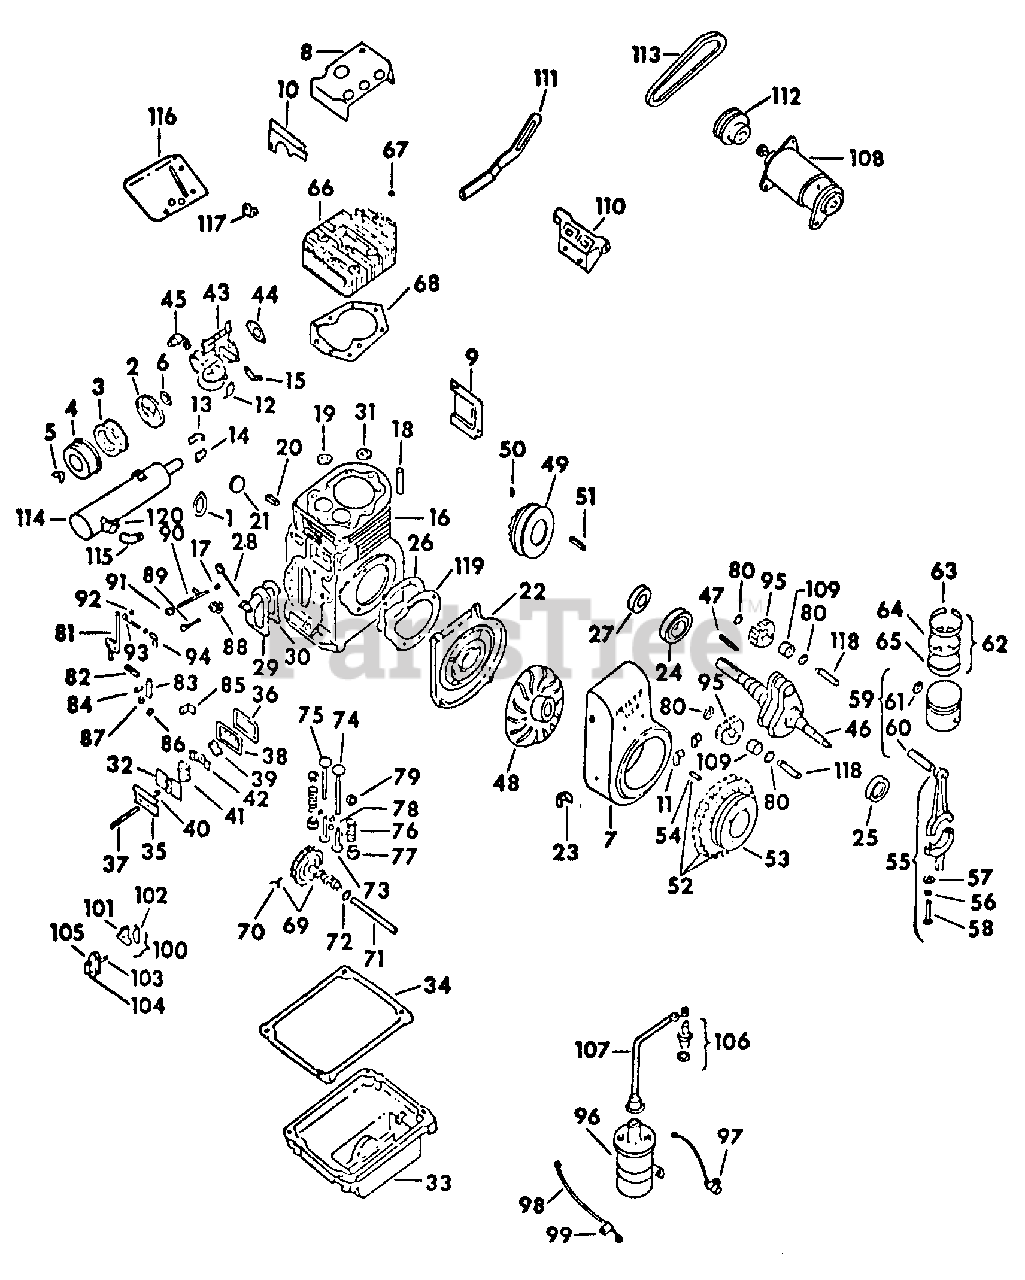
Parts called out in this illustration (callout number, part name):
1	Nut, Exhaust Muffler Elbow Lock
2	Base, Air Cleaner
3	Element, Air Cleaner Filter
4	Cover, Air Cleaner
5	Nut, Air Cleaner Wing
6	Gasket, Air Cleaner
7	Housing Assy, Blower
8	Baffle, Cylinder Head Air
9	Baffle, Cylinder Air
10	Baffle, Housing Side Air
11	Clip, Throttle Cable
12	Clip, Choke Cable
13	Bracket, Throttle Cable
14	Clip, Throttle Cable
15	Bracket, Choke
16	Block, Cylinder
17	Bearing, Needle
18	Guide, Valve
19	Insert, Exhaust Valve
20	Shaft, Governor
21	Plug, 1-1/8 Expansion (Crankcase)
22	Plate, Crankcase Bearing
24	Bearing, Crankcase Ball
25	Seal, Front Plate Oil
26	Gasket, Bearing Plate, .010
27	Seal, Crankcase Rear Oil
29	Cover, Camshaft
30	Gasket, Camshaft Cover
31	Insert, Intake Valve
32	Gasket, Valve Cover
33	Base, Oil Pan
34	Gasket, Oil Pan Base
35	Cover, Breather
36	Gasket, Breather
37	Stud, Breather Cover
38	Plate Assy, Breather
39	Reed, Breather
40	Seal, Breather
41	Filter, Breather
42	Baffle, Breather
43	Carburetor Assy
44	Gasket, Carburetor
45	Elbow, Carburetor to Fuel Line
47	Key, 3/16 X 3/8 Sq Parallel
49	Pulley w/Clutch Drive Plate, Flywheel
50	Screw, Flywheel Pulley Set
51	Key, 1/4 X 7/8 Sq Parallel
52	Cup Assy, Flywheel Drive
53	Screen, Drive Cup Grass
54	Pin, Flywheel Drive Cup
55	Rod Assy, Connecting, Std
56	Washer, Connecting Rod Lock
57	Washer, Connecting Rod
58	Screw, Connecting Rod
59	Piston Assy, Std
60	Pin, Piston
61	Retainer, Piston Pin
62	Ring Set, Piston, Std
63	Ring, Top Compression
64	Ring, Center Compression
65	Ring, Oil Control
66	Head, Cylinder
67	Washer, Cylinder Head
68	Gasket, Cylinder Head
69	Camshaft Assy
70	Spring, Camshaft Actuating
71	Pin, Camshaft
72	Shim, Camshaft, .005
73	Tappet Assy, Valve
74	Valve, Intake
75	Valve, Exhaust
76	Spring, Valve
77	Rotator, Valve
78	Key, Valve Spring
79	Retainer, Valve Spring Upper
80	Kit, Spacer
81	Lever, Governor
82	Spring, Governor
83	Bracket, Speed Control
84	Clamp, Control Bracket
85	Bracket, Adjusting Screw
86	Spacer, Adjusting Screw
87	Washer, Adjusting Screw Spacer
88	Gear Assy, Governor
89	Pin, Governor Stop
90	Shaft Assy, Governor Cross
91	Bushing, Cross Shaft
92	Rod, Ball Joint Throttle
93	Retainer, Throttle Rod
94	Joint, 10-32 X 1/4 Ball
95	Gear Assy, Crankshaft Balance
96	Coil, Ignition
97	Condenser, Ignition Coil
98	Cable Assy, Condenser to Breaker
99	Clip, Condenser to Breaker Cable
100	Not used in this application
101	Breaker Contact Set
102	Bracket, Breaker Point
103	Rod, Breaker
104	Cover, Breaker
105	Gasket, Breaker Cover
106	Plug, Spark (Champion)
107	Kit, Hi-Tension Cable Lead
108	Motor Generator
109	Bearing Assy, Needle
110	Bracket, Motor Generator Mounting
111	Brace, Motor Generator Adjusting
112	Pulley, Motor Generator Drive
113	Belt, Motor Generator Drive
114	Muffler, Exhaust
115	Elbow, Exhaust
116	Baffle, Heat
117	Strap, Lifting
118	Pin, Crankshaft
119	Gasket, Bearing Plate
120	Clamp, Muffler
